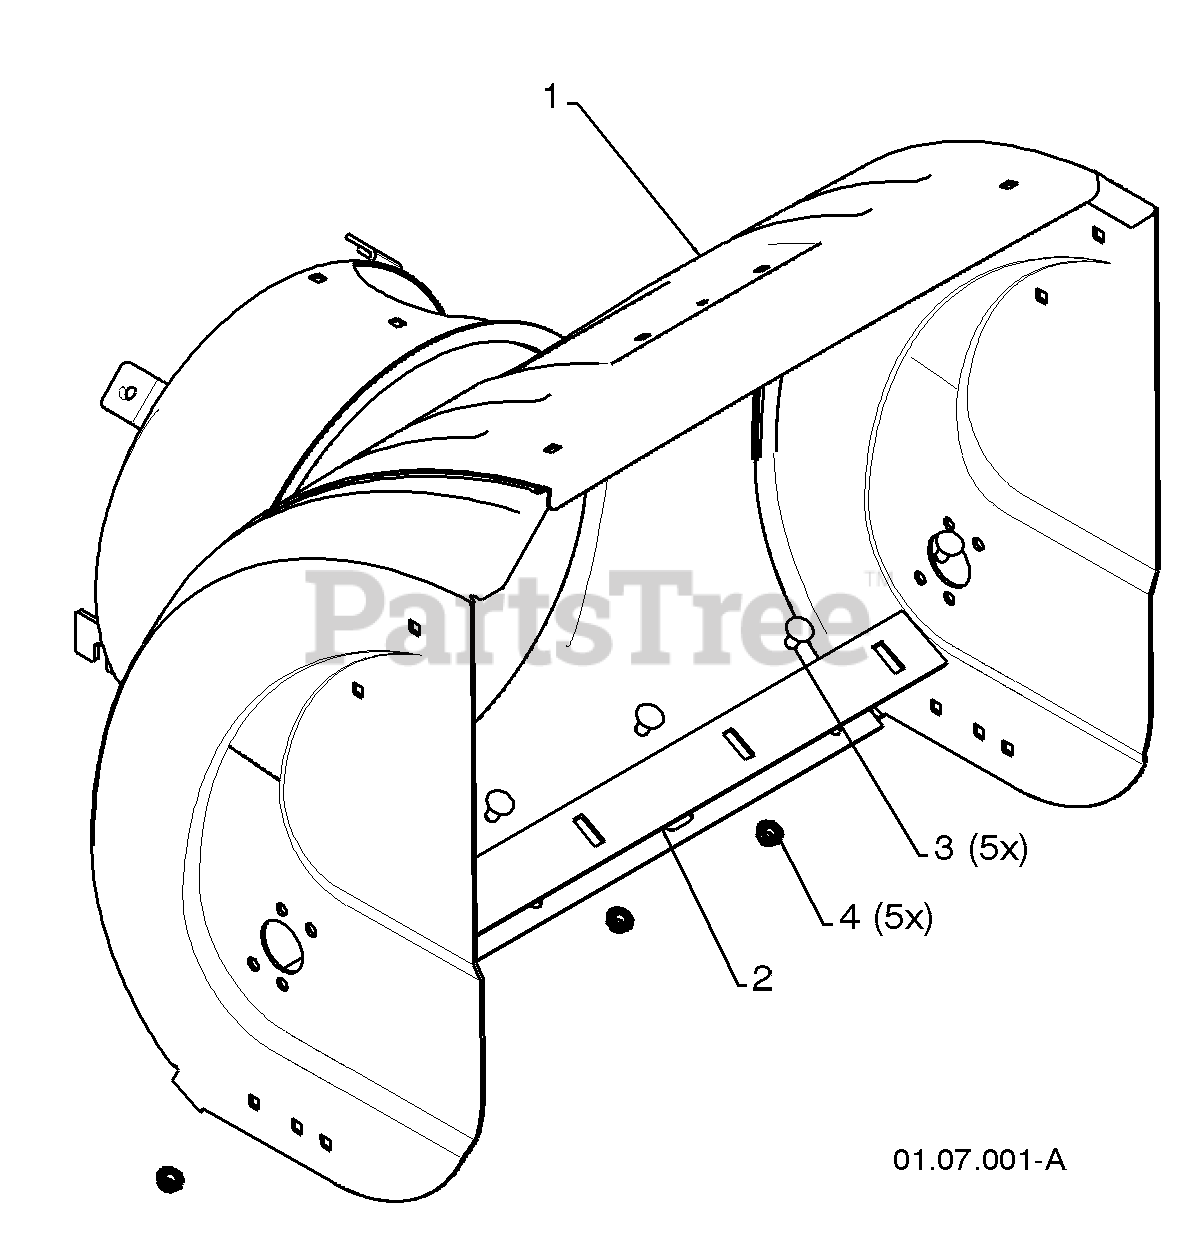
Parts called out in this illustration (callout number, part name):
1	AUGER HOUSING
2	SCRAPPER BAR
3	CARRIAGE BOLT 5/16-18 X .625
4	NUT 5/16-18
